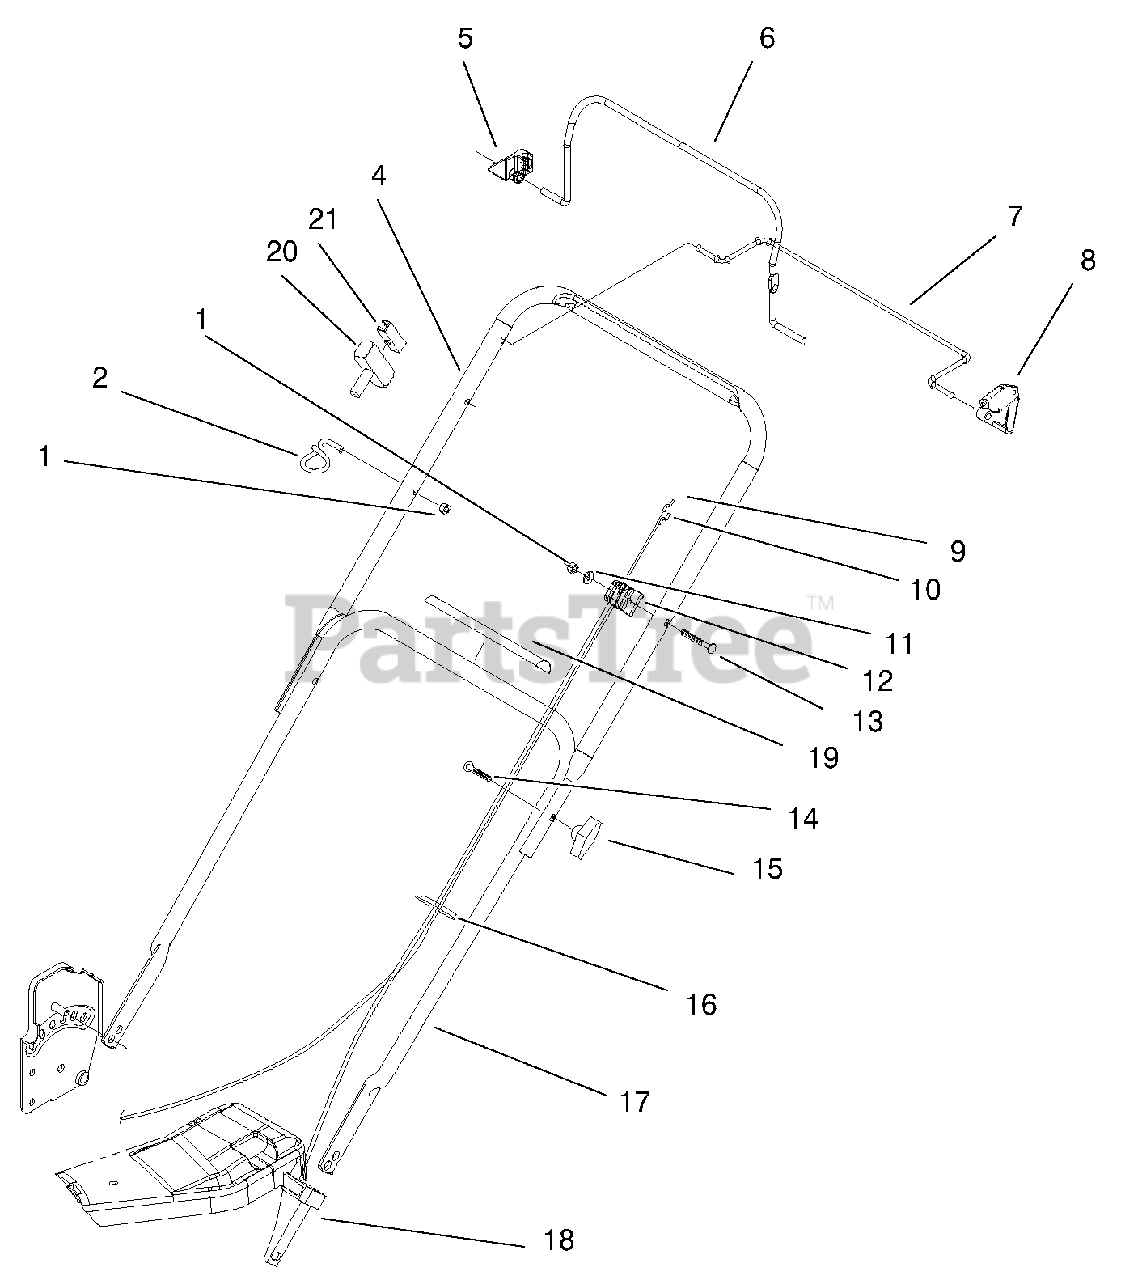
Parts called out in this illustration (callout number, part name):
1	Nut-Lock, NI
2	Guide-Rope
4	Handle-Upper
6	Bail-Brake
7	Bail-Traction
8	Stop-Pivot
9	Cable-Traction
10	Brake Cable ASM
11	Washer-Flat
12	Anchor-Cable
13	Screw-Handle
14	Screw-Handle
15	Knob-Handle
16	Tie-Cable
17	Lower Handle
18	Anchor-Cable
19	Decal-Operation
20	Handle-Start
21	Starter-Clip
